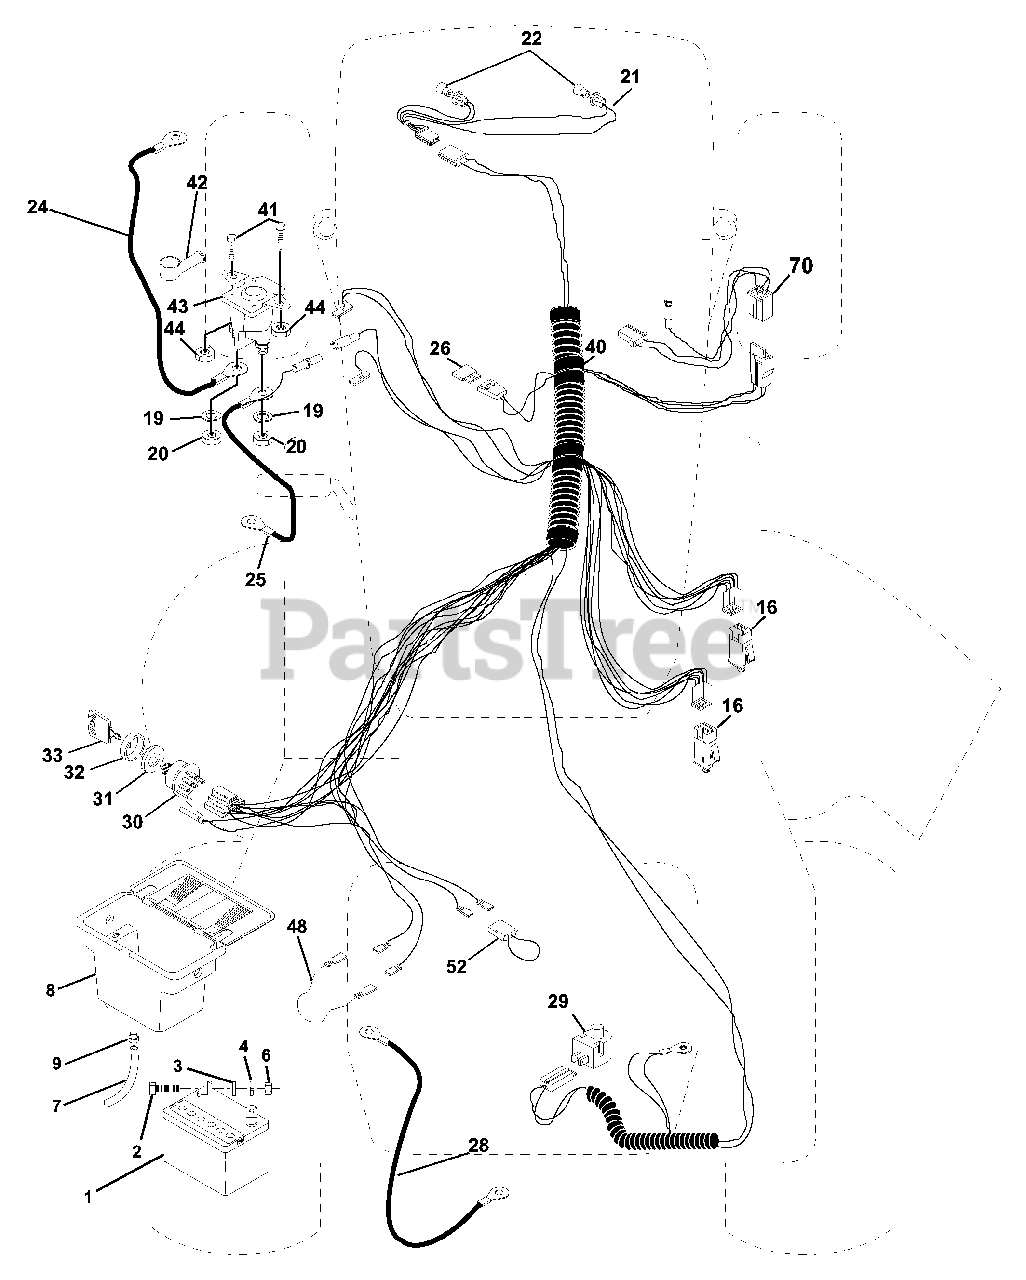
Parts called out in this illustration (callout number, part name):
1	Battery 12 Volt 25 AMP
2	Bolt Hex Hd 1/4-20unc X 3/4
3	Washer 9/32 X 5/8 X 16 Ga.
4	Washer Lock Hvy Helical 1/4
6	Nut Fin Hex 1/4-20 Unc
7	Tube Plastic 12"
8	Case Battery Mech Hinge
9	Clamp Hose Olive
16	Switch Interlock Push-In
19	Washer Lock 1/4
20	Nut Jam Hex 1/4-20 Unc
21	Harness Asm Light W/4152j
22	Bulb Light #1156
24	Cable Battery 6 Ga 11" red
25	Cable Battery 6 Ga 44" red w/16 wire
26	Fuse 30 AMP Auto Green
28	Cable Ground 6 Ga 12" black
29	Switch Plunger Nc Gray
30	Switch Ign 4 pos w/lights
31	Nut Ignition
32	Cover Sw Ignition
33	Key Ign Modelled Generic
40	Harness Ign.
41	Bolt Blk Fin Hex 1/4 - 20 x 1/2
42	Cover Terminal Red
43	Solenoid
44	Nut Keps Hex 1/4-20 Unc
48	Adapter Ammeter Rectangular
52	Protection Wire Loop
70	Harness, Eng. B&S/Tec Dual
